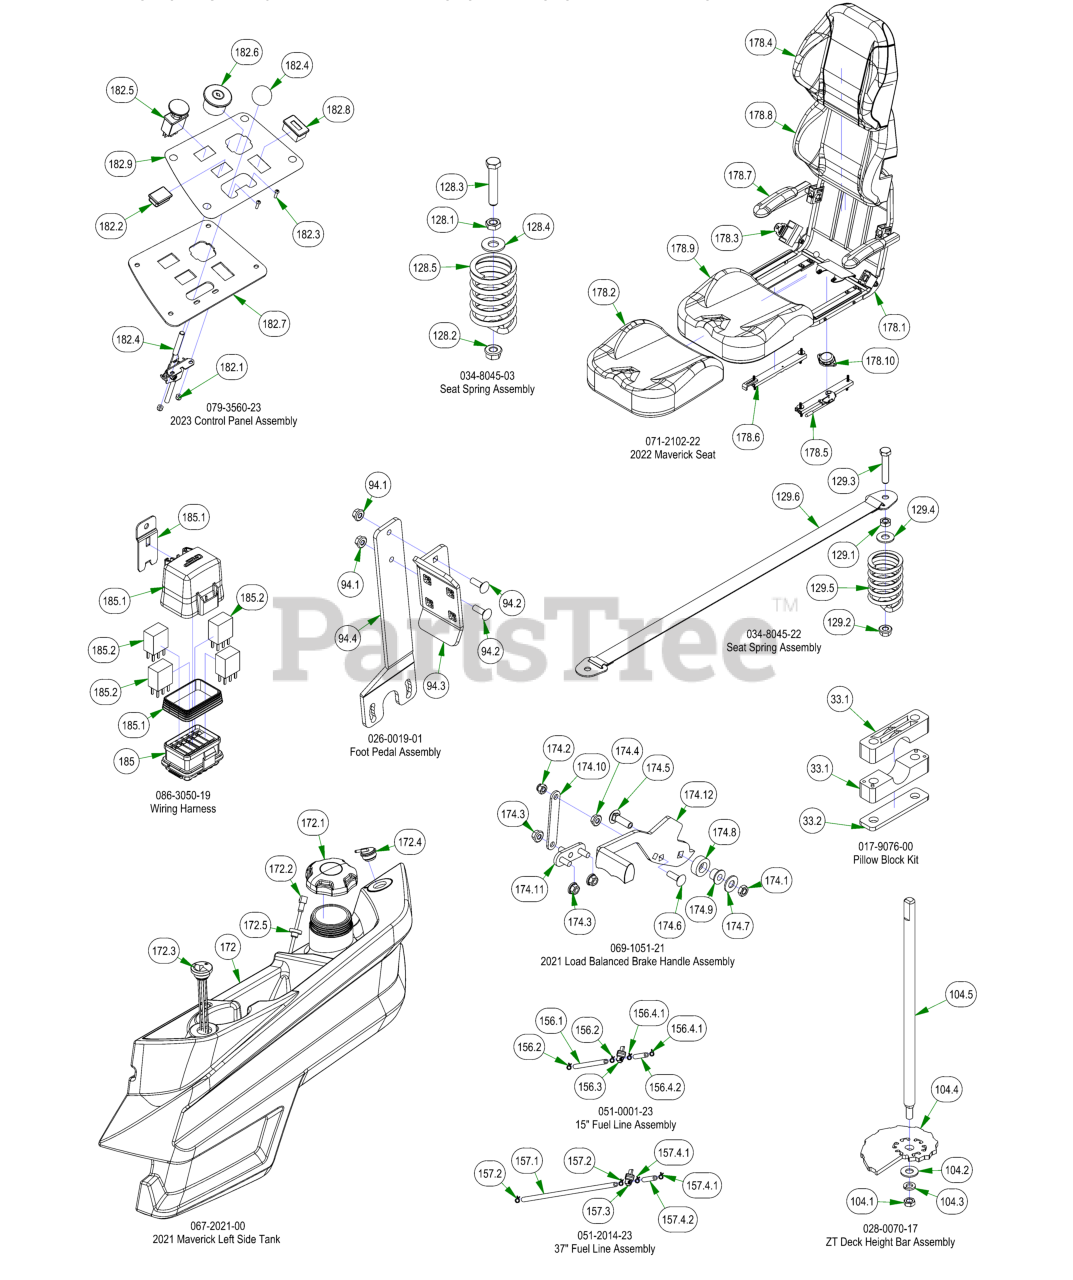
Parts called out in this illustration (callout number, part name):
33	Pillow Block Kit
33.1	Pillow Block MZ
33.2	Pillow Block Strap
94	Foot Pedal Assembly
94.1	5/16-18 NYLON INSERT FLANGE LOCKNUT ZINC
94.2	5/16-18 X 1 CARRIAGE BOLT (GR.8) ZINC
94.3	2017 MZ/ZT Shallow Foot Pedal
94.4	2017 MZ/ZT Deck Pedal Lever
104	ZT Deck Height Bar Assembly
104.1	3/8-24 HEX NUT ZINC YELLOW
104.2	3/8 FLAT WASHER USS (1" OD) ZINC
104.3	3/8 SPLIT LOCKWASHER ZINC
104.4	2017 MZ/ZT Cam Plate
104.5	2017 Deck Height Dial Rod ZT
128	Seat Spring Assembly
128.1	3/8-16 Half Jam Nut
128.2	3/8-16 HEX SERRATED FLANGE NUT HARD/ZINC
128.3	3/8-16 X 2 HEX CAP SCREW (GR.5) ZINC
128.4	3/8 FLAT WASHER USS (1" OD) ZINC
128.5	Seat Spring
129	Seat Spring Assembly
129.1	3/8-16 Half Jam Nut
129.2	3/8-16 HEX SERRATED FLANGE NUT HARD/ZINC
129.3	3/8-16 X 2 HEX CAP SCREW (GR.5) ZINC
129.4	3/8 FLAT WASHER USS (1" OD) ZINC
129.5	Seat Spring
129.6	Seat Strap with Buckles
156	15" Fuel Line Assembly
156.1	11" 1/4 Fuel Line
156.2	1/4 Fuel Hose Clamp
156.3	2 Way Fuel Shut-Off Valve
156.4	Fuel Line 4" Section with Clamps
156.4.1	1/4 Fuel Hose Clamp
156.4.2	4" 1/4 Fuel Line
157	37" Fuel Line Assembly
157.1	37" 1/4 Fuel Line
157.2	1/4 Fuel Hose Clamp
157.3	2 Way Fuel Shut-Off Valve
157.4	Fuel Line 4" Section with Clamps
157.4.1	1/4 Fuel Hose Clamp
157.4.2	4" 1/4 Fuel Line
172	2021 Maverick Left Side Tank
172.3	Fuel Gauge w/Grommet
172.4	Rollover Valve W/Grommet
172.5	Pick-Up Grommet
174	2021 Load Balanced Brake Handle Assembly
174.1	3/8-16 HEX JAM 2-WAY REVERSIBLE CENTER LOCKNUT ZINC
174.2	5/16-18 NYLON INSERT CAP LOCKNUT ZINC (BLK CAP)
174.3	5/16-18 NYLON INSERT FLANGE LOCKNUT ZINC
174.4	5/16-18 HEX SERRATED FLANGE NUT HARD/ZINC
174.5	3/8-16 X 1-1/4 CARRIAGE BOLT ZINC
174.6	5/16-18 X 1 CARRIAGE BOLT (GR.8) ZINC
174.7	3/8 FLAT WASHER USS (1" OD) ZINC
174.8	2015 Brake Lever Spacer
174.9	.377 ID X .625 OD X .500 HGT X .880 FLNG DIA X .060 FLNG THK
174.10	Brake Cable Extension Plate
174.11	Brake Load Balancer Lower Weldment
174.12	Load Balanced Brake Handle with Grip
178	2022 Maverick Seat
178.1	400 Series Universal Mount Frame 3/4"
178.2	Seat Cover
178.3	Seat Belt Set
178.4	Back Cover
178.5	Bad Boy Seat Slide
178.6	Bad Boy Slave Slide
178.7	Poly Pad w/ Shorter AFT Bracket
178.8	Seat Back Mold
178.9	Seat Bottom Mold
178.10	Seat Switch
182	2023 Control Panel Assembly
182.1	10-24 Nylon Insert Locknut Zinc Orange Nylon
182.2	Light Plug
182.3	10-24 X 5/8 BS Button Head Bolt
182.4	Throttle Lever Assembly
182.5	PTO Engager
182.6	Ignition Switch
182.7	2022 Maverick HD control panel
182.8	Tachometer
182.9	2023 MZ/Magnum/ZT/Maverick Control Panel Decal
185	Wiring Harness
185.1	Relay Block Cover Replacement Kit
